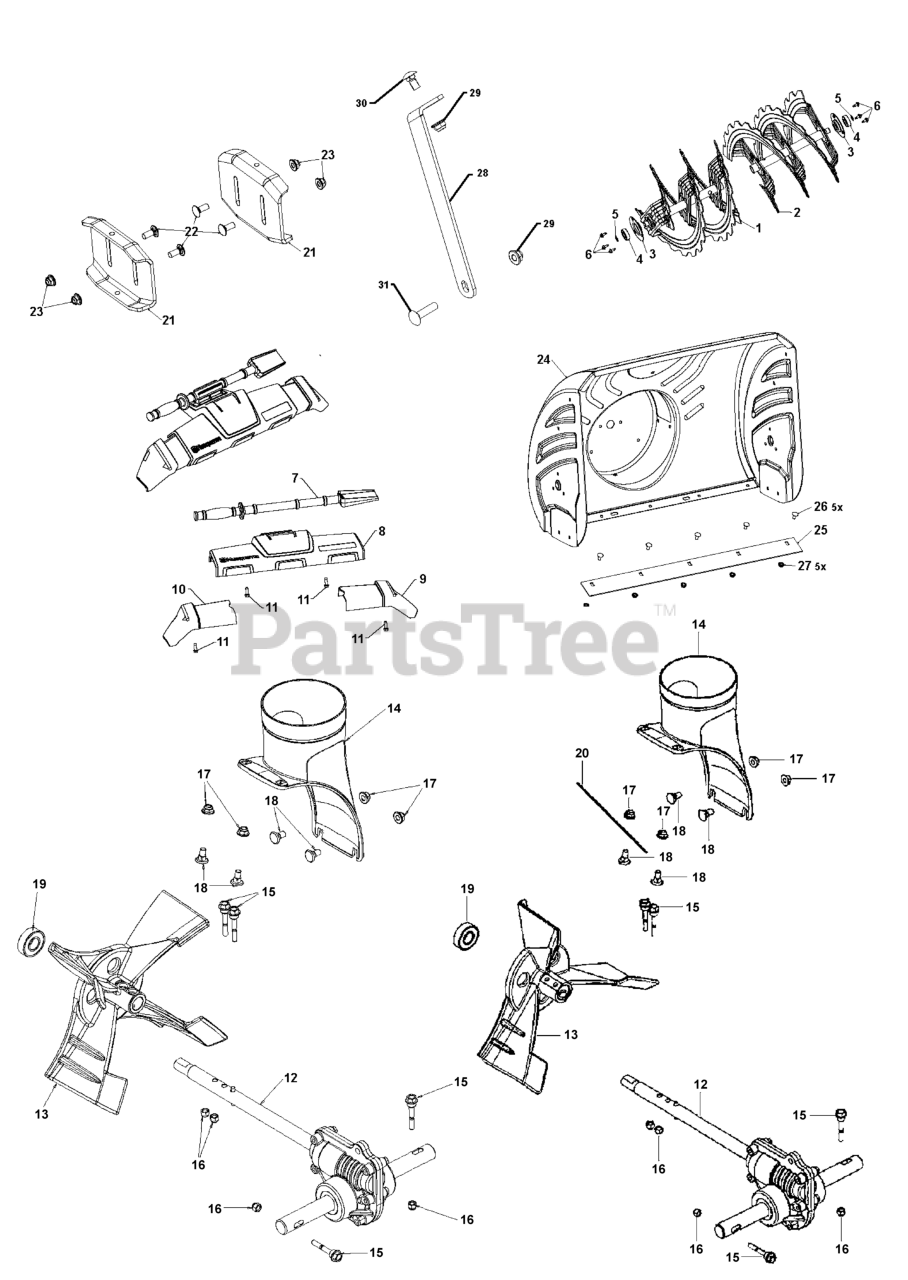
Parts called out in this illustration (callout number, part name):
1	AUGER.RIB.30.RH.LS.GREY
2	AUGER.RIB.30.LH.LS.GREY
3	SUPPORT.BEARING.SINGLE.STAGE.B
5	RETAINING RING LT
6	HEX.WASHER.HEAD 1/4-20 X .65
7	CLEAN OUT TOOL
8	TRIM AUGER FRONT TRIM ASSEMBLY
9	TRIM AUGER.HOUSING.WING.RH MS
10	TRIM AUGER.HOUSING.WING.LH MS
11	SCREW 14-20 X 5/8
12	GEARBOX CAST DD SHAFT
13	IMPELLER CAST.IRON.12IN MS 417
13	Blades
14	CHUTE BASE CAST ALUM HUSQ SIL
15	BOLT SHEAR HX HD 1/4-20 CLEAR
16	NUT HEXAGON 1/4-20 ST ZPB
17	NUT HEX FLG NYLOCK BLK 5_16-1
18	BOLT CARR WAFER BLK 5_16-18 X
21	SKID PLATE
22	BOLT CARR BLK 5_16-18 X .750
23	NUT HEX FLG NYLOCK BLK 5_16-1
24	HOUSING ASSY KIT LS.NF.668 (30
25	PLATE.SHAVE.30.LS.SNOW.BLACK
26	BOLT ROUND HEAD SQUARE NECK BO
27	GSPW Hardware
27	NUT.FLANGE.5/16
28	SUPPORT.GEARBOX.LS.498
29	NUT HEX FLG NYLOCK BLK 5_16-1
30	BOLT CAR BLK 5/16-18 X 5/8
31	BOLT.CARRIAGE.5/16-18
